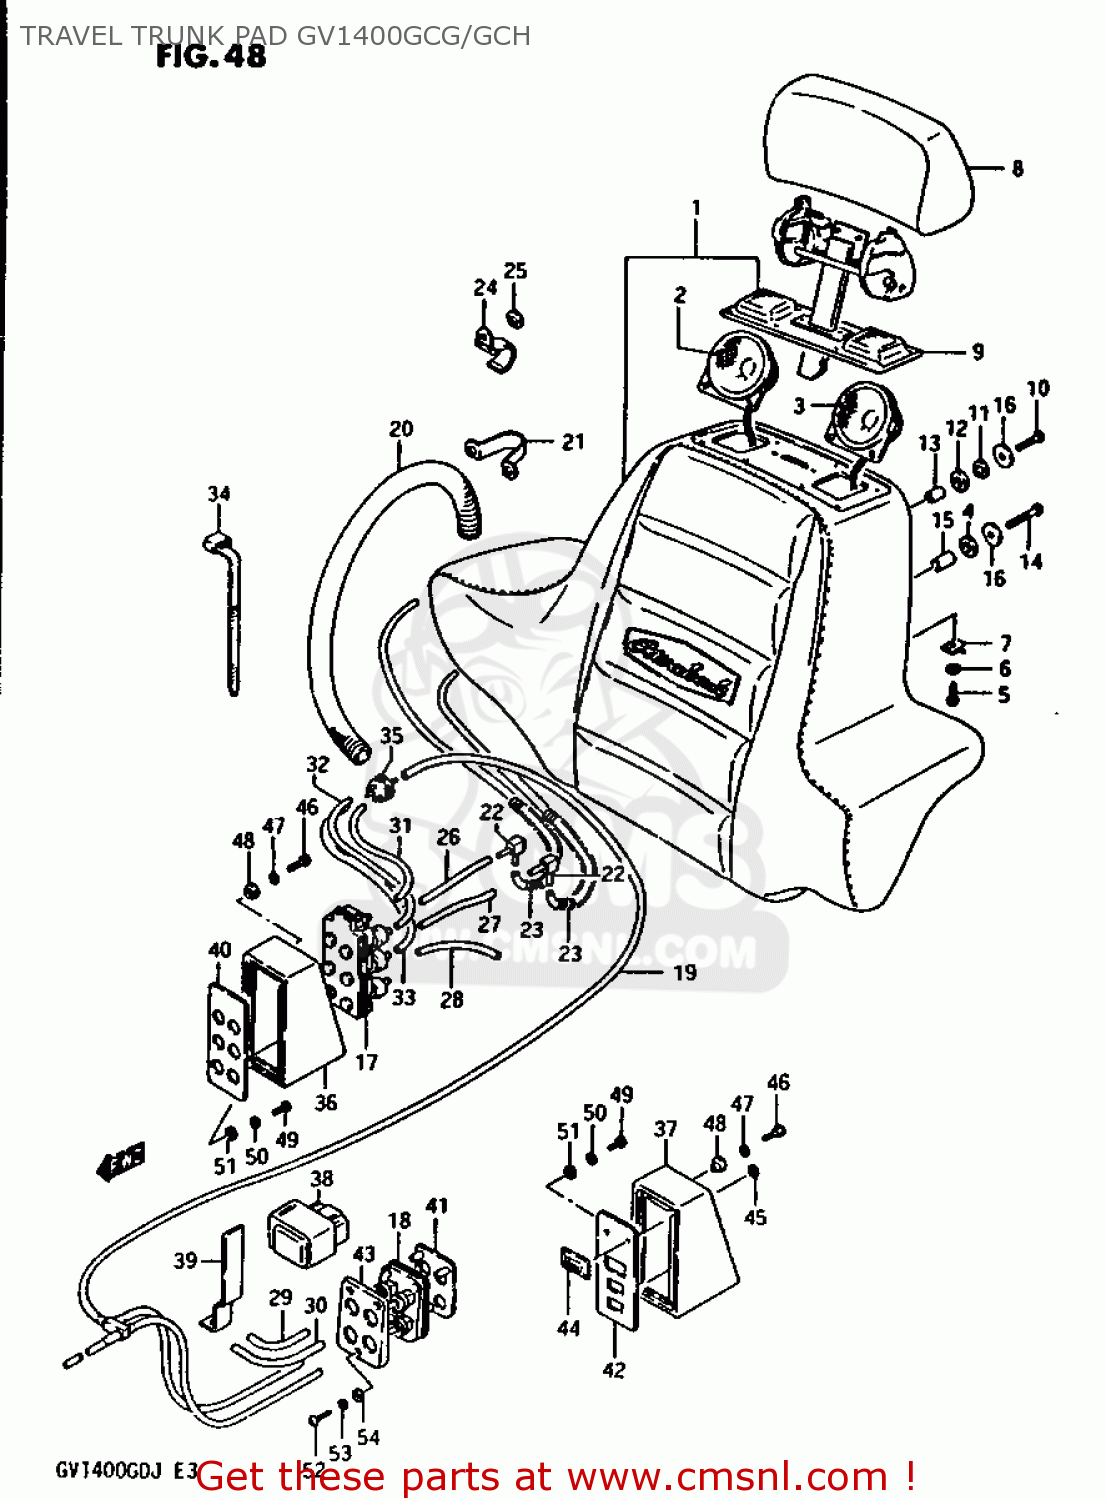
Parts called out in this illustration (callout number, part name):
1	SEAT ASSEMBLY,PILLION
2	SPEAKER
3	SPEAKER ASSEMBLY,REAR,LEFT
4	CUSHION,PAD ASSEMBLY NO.2
5	SCREW
6	WASHER
7	NUT
8	PAD ASSEMBLY,HEAD REST
9	ADJUSTER,HEAD REST
10	SCREW
11	SEAL,PAD ASSEMBLY,RIGHT
12	WASHER
13	SPACER
14	SCREW (6X40)
15	SPACER
16	WASHER (6.5X22X1.6)
17	VALVE ASSEMBLY,SEAT
18	VALVE ASSEMBLY,SEAT,FRONT
19	HOSE ASSEMBLY,AIR SEAT NO
20	PROTECTOR, TRUNK HOSE
21	HOLDER, TRUNK HOSE
22	UNION
23	SPRING
24	CLAMP
25	SEAL,PAD ASSEMBLY,RIGHT
26	HOSE, OUTLET NO.1
27	HOSE, OUTLET NO.2
28	HOSE, OUTLET NO.3
29	HOSE, OUTLET NO.4
30	HOSE, OUTLET NO.5
31	HOSE, INLET NO.1
32	HOSE, INLET NO.2
33	HOSE, INLET NO.3
34	CLAMP(L:165)
35	4-WAY
36	PAD ASSEMBLY,TRAVEL TRUNK
37	PAD ASSEMBLY,TRAVEL TRUNK
38	RELAY ASSEMBLY,SEAT
39	BRACKET, SEAT RELAY
40	PANEL COMP,VALVE ASSEMBLY
41	PANEL,VALVE ASSEMBLY,FRONT
42	PANEL COMP,TUNER ASSEMBLY
43	SPACER,PANEL VALVE,FRONT
44	EMBLEM
45	NUT
46	BOLT, PAD
47	WASHER,LOCK
48	WASHER
49	SCREW
50	WASHER,LOCK 4M
51	WASHER 4MM
52	SCREW
53	WASHER,LOCK 4M
54	WASHER 4MM
